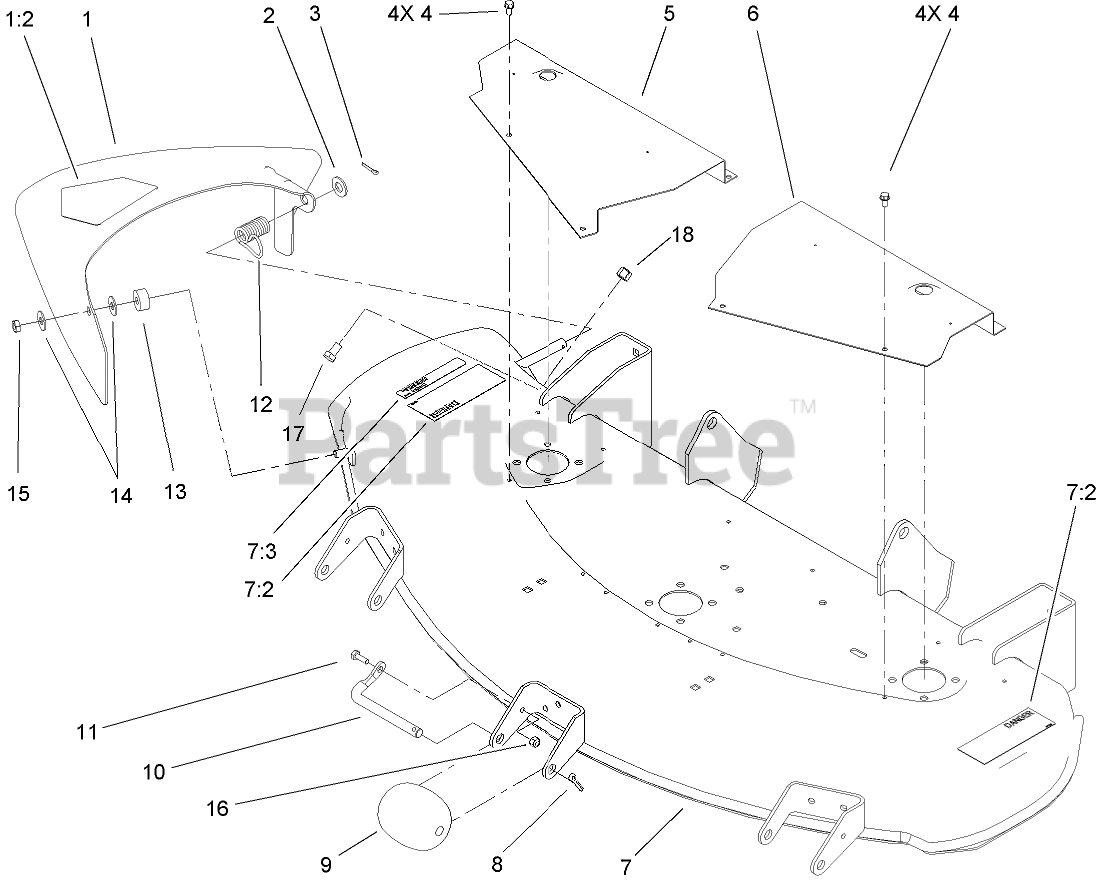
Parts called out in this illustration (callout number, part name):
1	CHUTE ASM
1:2	DECAL-DANGER
2	WASHER-FLAT
3	PIN-COTTER
4	SCREW-HWH
5	COVER-BELT, RH
6	COVER-BELT, LH
7	DECK AND DECAL ASM
7:2	DECAL-DANGER
7:3	DECAL-CAUTION
8	PIN-COTTER
9	ROLLER
10	Shaft-Roller
11	SCREW-HH
12	SPRING-DEFLECTOR
13	BUSHING-PIVOT
14	WASHER
15	NUT-JAM
16	NUT-LOCK, NI
17	SCREW-HH
18	NUT-LOCK, NI
